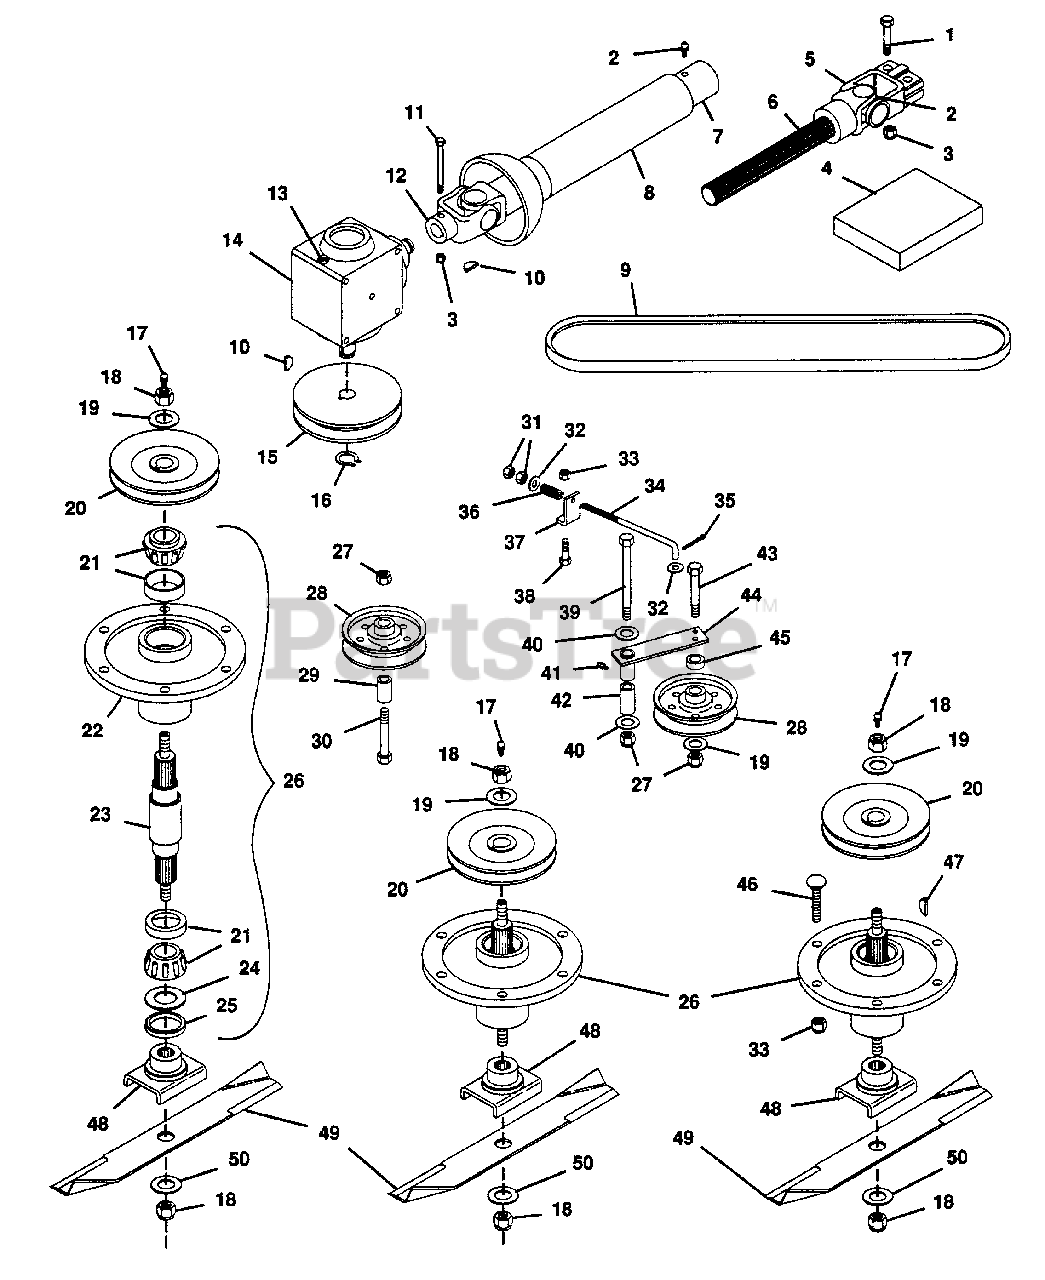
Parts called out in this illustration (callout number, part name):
1	Bolt, Hex 5/16-18x1.75
2	Fitting, Lube 1/4-28
3	Nut, Lock 5/16-18
4	Kit, Repair U-Joint
5	Yoke
6	Assembly, U-Joint Male
7	Assembly, U-Joint Female
8	Cover, U-Joint
9	Belt, Vee 60" Mower
10	Key, Woodruff .25x.875 Hard #A
11	Bolt, Hex 5/16-18x2.25
12	Yoke
13	Plug, 1/8 Vent
14	Gearbox, Right Angle 1:1
15	Sheave, Gear Box
16	Ring, Retaining .875 Shaft
17	Fitting, Lube 1/8
18	Nut, Lock 5/8-11
19	Washer, Flat .687x1.312x.122
20	Weldment, Spindle Sheave
21	Assembly, Bearing
22	Housing, Bearing
23	Shaft, Spindle
24	Washer, Flat .975x1.970x.030
25	Seal, Steel
26	Assembly, Spindle
27	Nut, Lock 1/2-13
28	Pulley, Flat Idler
29	Bush., St. .562x.975x1.00 Stl.
30	Bolt, Hex 1/2-13x2.75
31	Nut, Hex 3/8-24
32	Washer, Flat .406x.812x.065
33	Nut, Lock 3/8-16
34	Rod, Idler
35	Pin, Cotter .094x.75
36	Spring, Comp. 1x.78x338
37	Support, Spring ÒB"
38	Bolt, Hex 3/8-16x1.125
39	Bolt, Hex 1/2-13x3.75
40	Washer, Flat .500x1.250x.083
41	Fitting, Lube 1/4-28
42	Bush., St. .505x.855x2.50 Stl.
43	Bolt, Hex 1/2-13x2.00
44	Weldment, Idler Pivot
45	Bush., St. .516x.875x.300 Stl.
46	Bolt, 3/8-16x1.375 Rd Hd Sq Nk
47	Key, Woodruff .25x1.00 Hard #15
48	Weldment, Blade Cradle
49	Blade
50	Washer, Flat .656x1.312x.095
